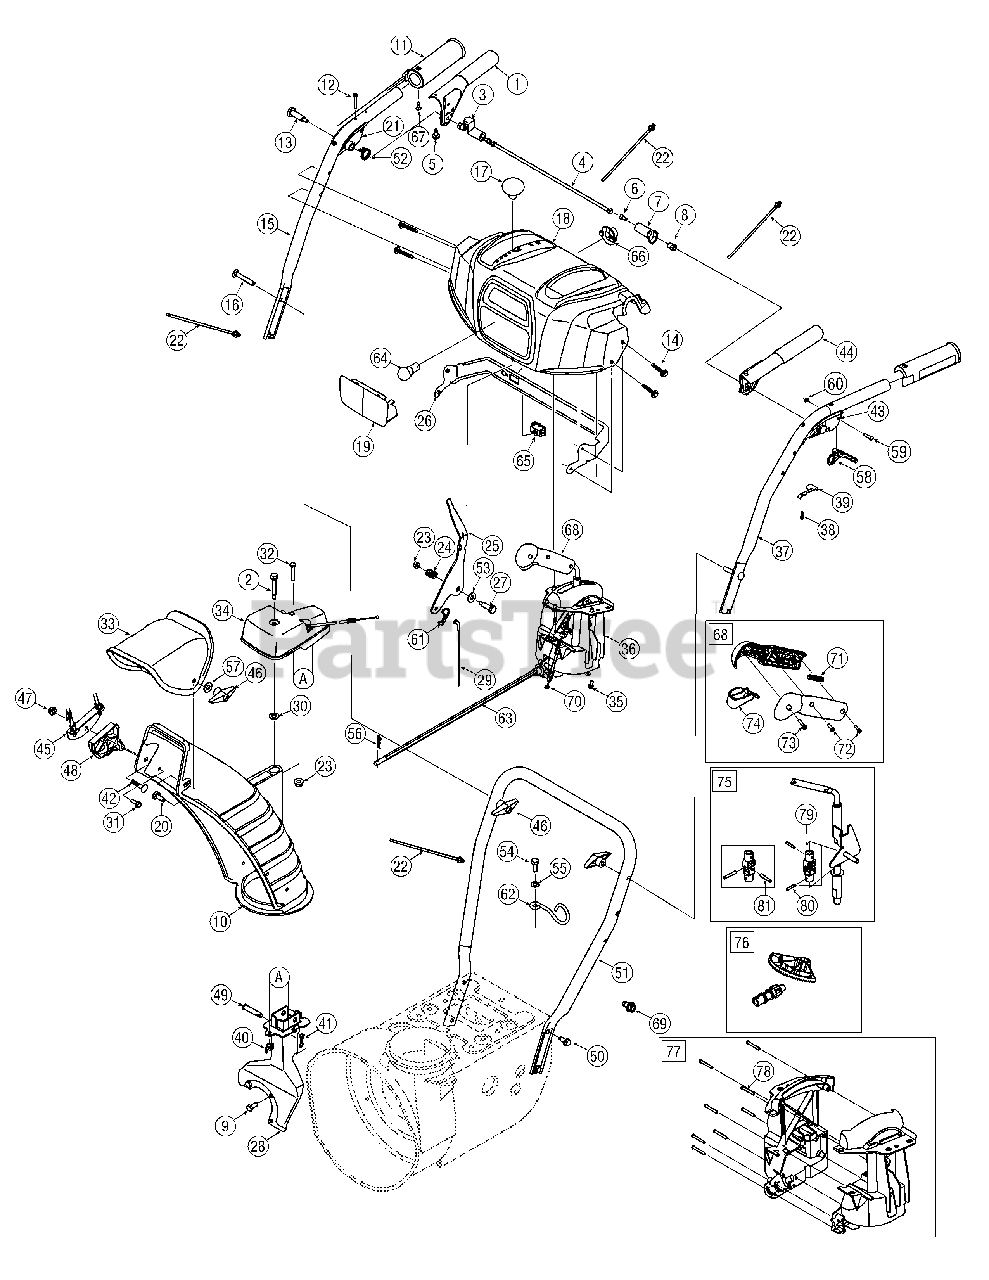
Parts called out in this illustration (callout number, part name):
1	Handle Engagement Assembly RH
2	Flange Shoulder Screw
3	Lock Plate
4	Pivot Rod
5	Rubber Bumper
6	Screw, 1/4-20 x .500
7	Clutch Lock Cam
8	Shoulder Nut, 1/4-20
9	Hex Screw, 5/16-24 x .750
10	Lower Chute
11	Heated Grip
12	Screw, #10-24 x 0.375
13	Shoulder Screw, 1/4-20
14	Screw, 1/4-20 x 1.625
15	Upper Handle RH
16	Carriage Screw, 5/16-18 x 2.25
17	Shift Knob
18	Handle Panel
20	Carriage Bolt, 5/16-18 x 1.0
21	Handle Clutch Lock Assembly - RH
22	Cable Tie
23	Flange Lock Nut, 1/4-20
24	Compression Spring
25	Shift Lever
26	Panel Bracket
27	Shoulder Screw
28	Chute Support Bracket
29	Speed Selector Cable
30	Flat Washer, .25 x .630 x .0515
31	Hi-Lo Screw, 1/4-15 x .75
32	Hex Screw, 1/4-20 x 3.00
33	Upper Chute
34	4-Way Chute Gearbox Assembly
35	Hi-Lo Screw, 1/4-15 x 0.5
36	4-Way Chute Control™ Assembly
37	Upper Handle LH
38	Screw, #8-16 x 0.50
39	Clutch Lock Spring
40	Wing Nut, 1/4-20
41	Bow Tie Cotter Pin
42	Carriage Bolt, 5/16-18 x 1.50
43	Handle Clutch Lock Assembly - LH
44	Handle Engagement Assembly LH
45	Cable Bracket
46	Wing Knob
47	Flange Lock Nut, 5/16-18
48	Chute Tilt Cable Guide
49	Clevis Pin
50	Screw, 5/16-18 x 0.75
51	Lower Handle
52	Torsion Spring
53	Flat Washer
54	Screw, M8-1.25
55	Flat Washer, .330 x .630 x .0635
56	Cotter Pin
57	Flat Washer, .349 x .879 x .063
58	Steering Control
59	Pin, 3/16
60	E-Ring
61	Click Pin
62	Cable Guide
63	Chute Rod
65	Switch, Heated Grip
66	Light Socket
67	Screw, #10-16 x .625
68	Handle Assembly
69	Screw (For ground wire)
70	4-Way Cable
71	Handle Plunger
72	Screw, Mach., #8-32 x .750
73	Screw, #8 x 1.00
74	Handle Lever
75	Shift Assembly
76	Gear Set Assembly
77	Handle Housing Assembly
78	Screw, #8-18 x 1.250
79	Joint Block Assembly
81	Roll Pin
